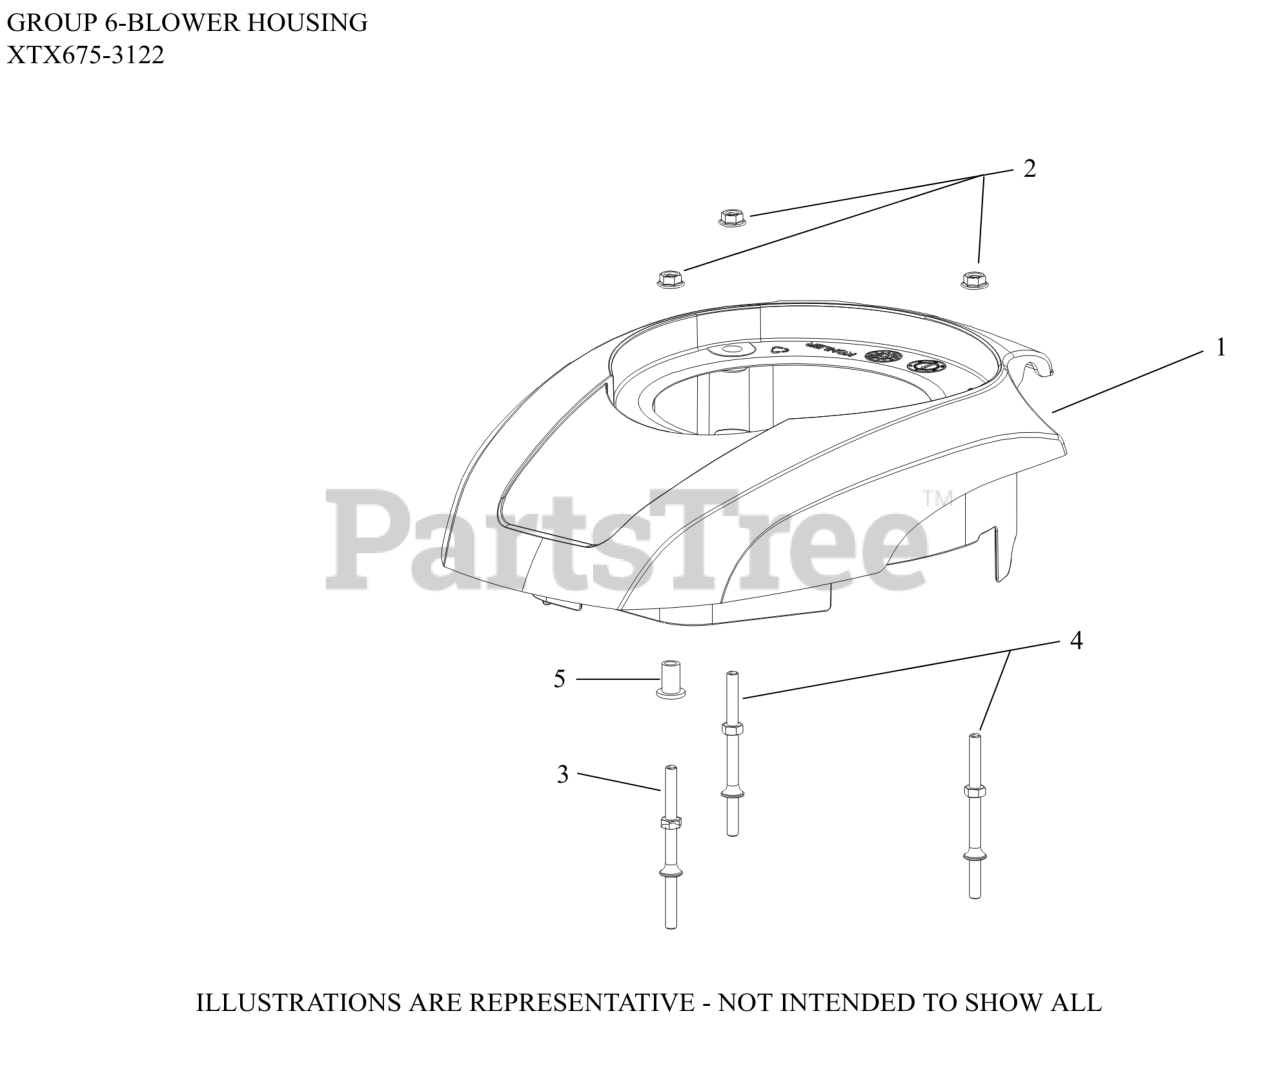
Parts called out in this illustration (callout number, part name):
1	COVER, ENGINE
2	NUT, HEX FLANGE (M6) - USE 14 100 16-S
3	STUD-USE 14 072 25-S
4	STUD-USE 14 072 26-S
